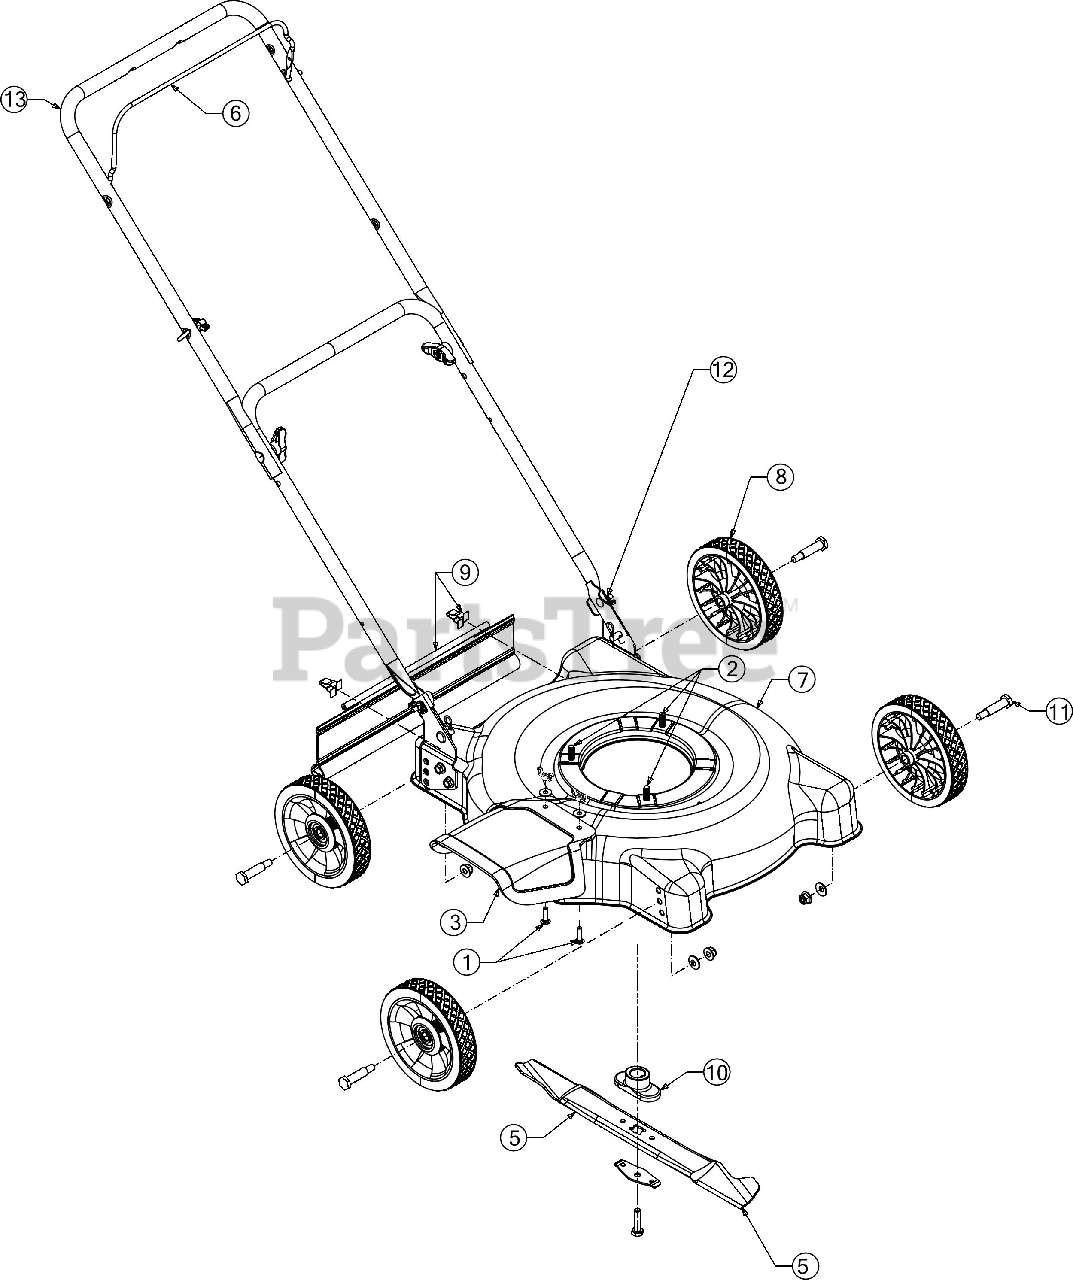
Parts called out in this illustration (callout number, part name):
1	SCREWPACK ASSEMBLY
2	SCREW 3/8-16 X 1
3	FIXED CHUTE
4	GREASE
5	20" BLADE
